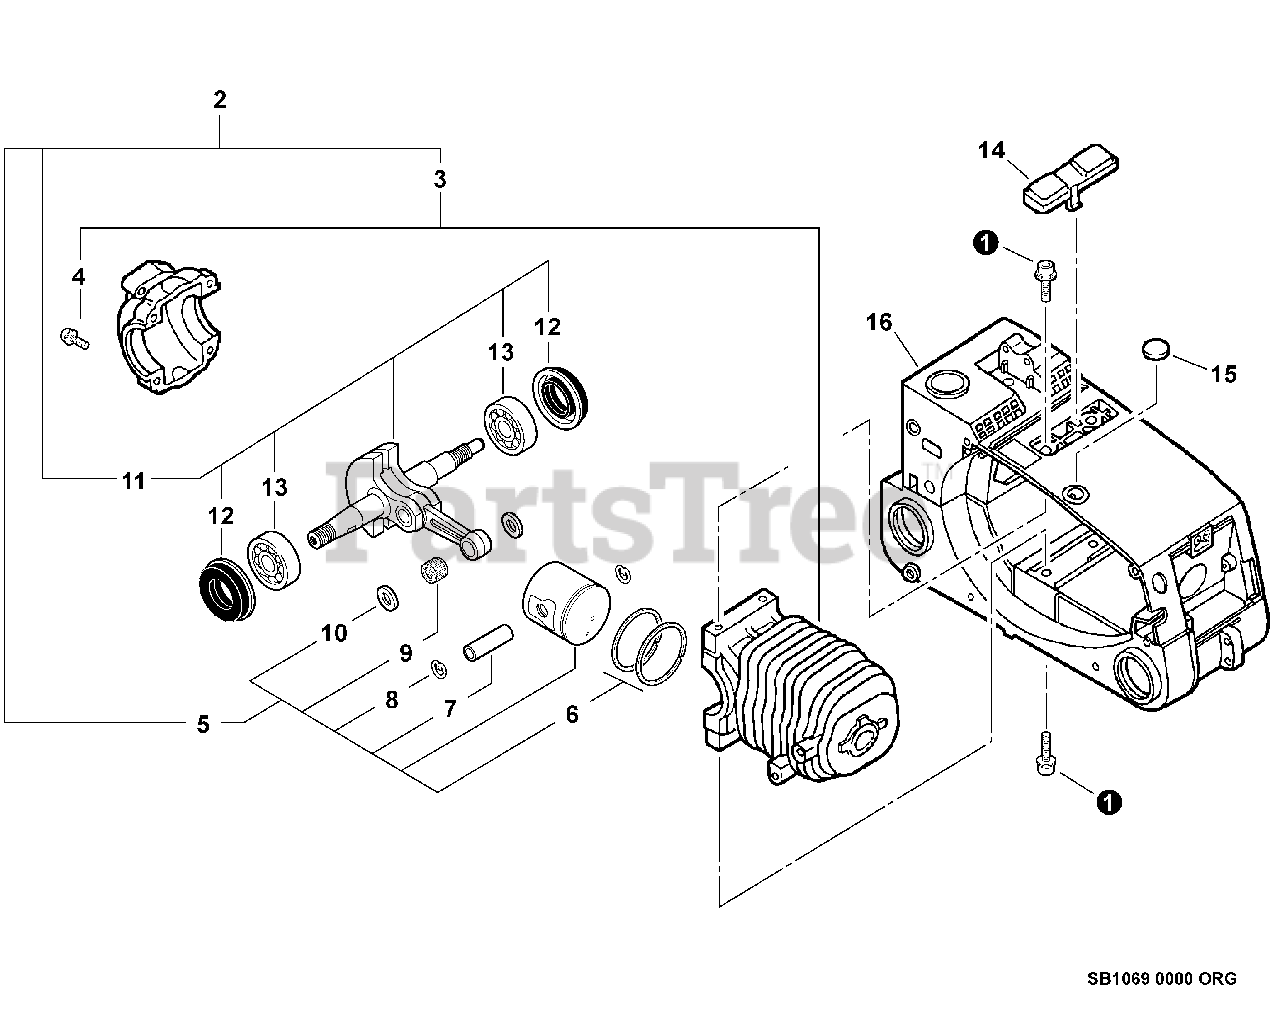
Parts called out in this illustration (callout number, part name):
1	BOLT 5×16
2	SHORT BLOCK
3	CRANKCASE SET
4	SCREW 5×25
5	PISTON KIT
6	RING, PISTON
7	PIN, PISTON
8	RING, SNAP
9	BEARING, NEEDLE 8
10	WASHER, THRUST
11	CRANKSHAFT ASSY
12	SEAL, OIL 12
13	BEARING, BALL - 6201 C3
14	COVER, TOP
16	COVER, ENGINE - ORANGE
